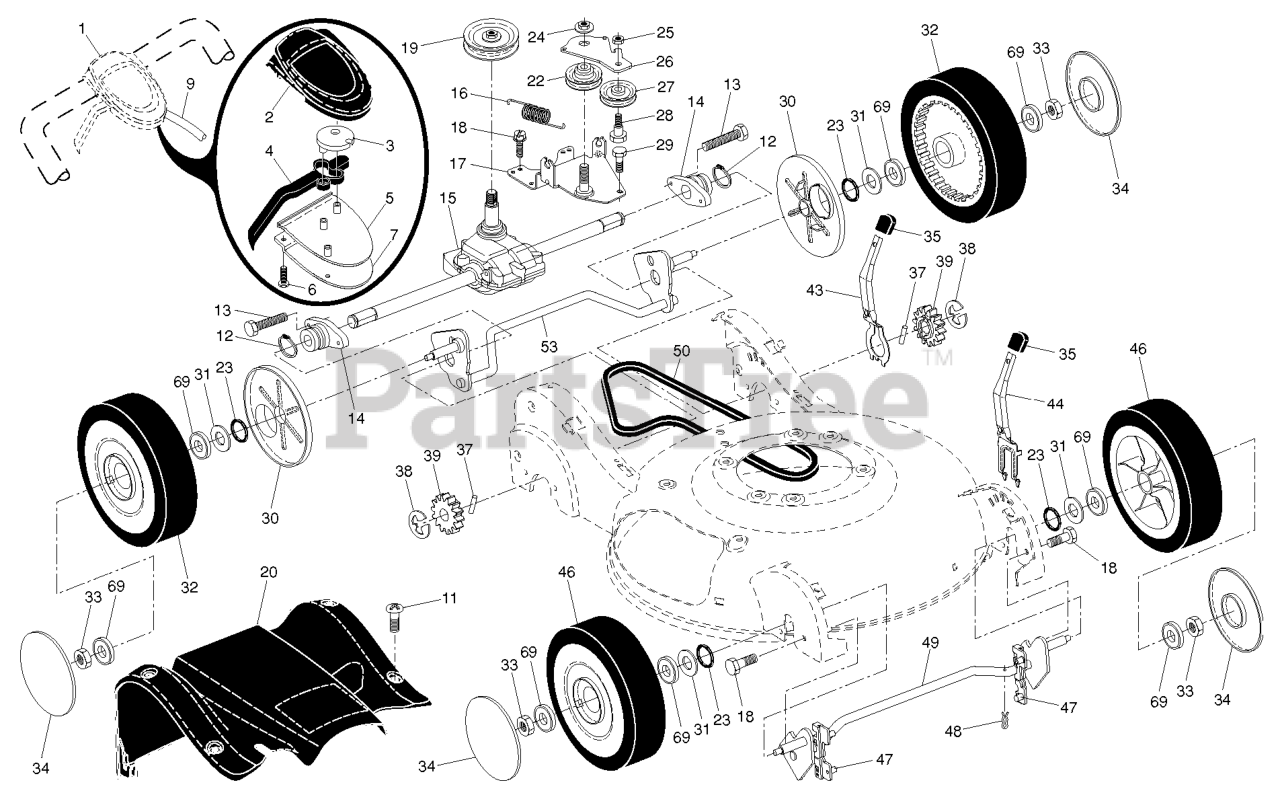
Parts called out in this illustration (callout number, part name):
1	CONTROL.DR.HV.RWGD.GRY/BLU
2	COVER TOP AUTO WALK CONTROL
3	PULLEY.CAM.DRIVE.CONTROL.HV
4	LEVER
5	COVER BOTTOM AUTO WLK CONTROL
6	SCREW, PHILLIPS HEAD 10 X 5/8
7	BRACKET.DRIVE.CONTROL.MOUNT.BL
9	ASM.CABLE.
12	RETAINING RING (2 2)(3 2)
13	SCREW.1/4-20X21/4.HEX.
14	BEARING / AXLE SUPPORT
15	TRANSMISSION.21.HV.RWGD.AW/EZ
17	BRACKET, GEAR CASE / DRIVE
19	RP PULLEY.DRIVE.EZ
20	COVER.DRIVE.REAR.21.HV.GRAY
22	PULLEY.IDLER.V-BELT
23	O-RING..070X.487.NEOPRENE
24	NUT.HEX.FLANGE.3/8-16.LOCKNUT
25	NUT.CENTERLOCK.5/16-
26	ARM.IDLER.BZP
27	IDLER PULLEY
28	SHOULDER BOLT
29	SCREW 14-20 X 5/8
30	DUST COVER, WHEEL
31	WASHER.FLAT.1/2
32	WHEEL.9X2.25.LP.TIGER.BLACK
33	NUT.HEX.FLANGE.3/8-16.LO(3 2)
34	HUBCAP.WHEEL.5.SPOKE.SILVER
35	KNOB.SELECTOR.SPRING.BLACK(3 2
37	PAWL, DRIVE
38	E-RING 7/16 RE
39	PINION.14.TEETH.FGD
43	LEVER, SELECTOR, HEIGHT, REAR
44	LEVER, SELECTOR, HEIGHT, FRONT
46	WHEEL.9X2.25.LP.TIGER.BLK
47	BUSHING.FRONT.TORQUE.SHAFT
48	SPRING RETAINER
49	SHAFT FRONT
50	BELT, DRIVE
53	SHAFT.ASM.REAR.TORQUE.HV.BZP
69	BEARING.8".WHEEL
